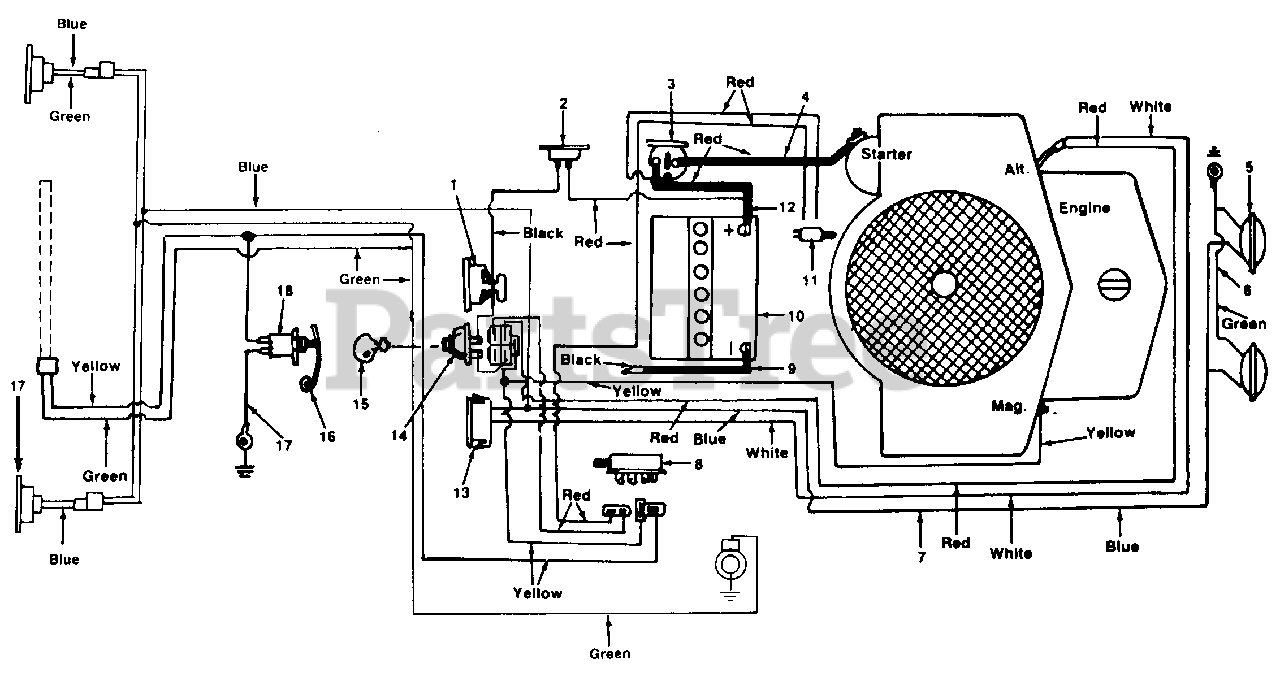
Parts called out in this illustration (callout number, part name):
1	Circuit Breaker
2	Solenoid
3	Wire
4	Safety Switch
5	Ground Wire
6	Head Light
7	Wire Harness
8	Safety Switch
9	6 Ga. Black Wire
10	Battery 12V
12	Ammeter
13	Light Switch
14	Ignition Switch
15	Ignition Key
16	Spring Switch
17	Taillights
